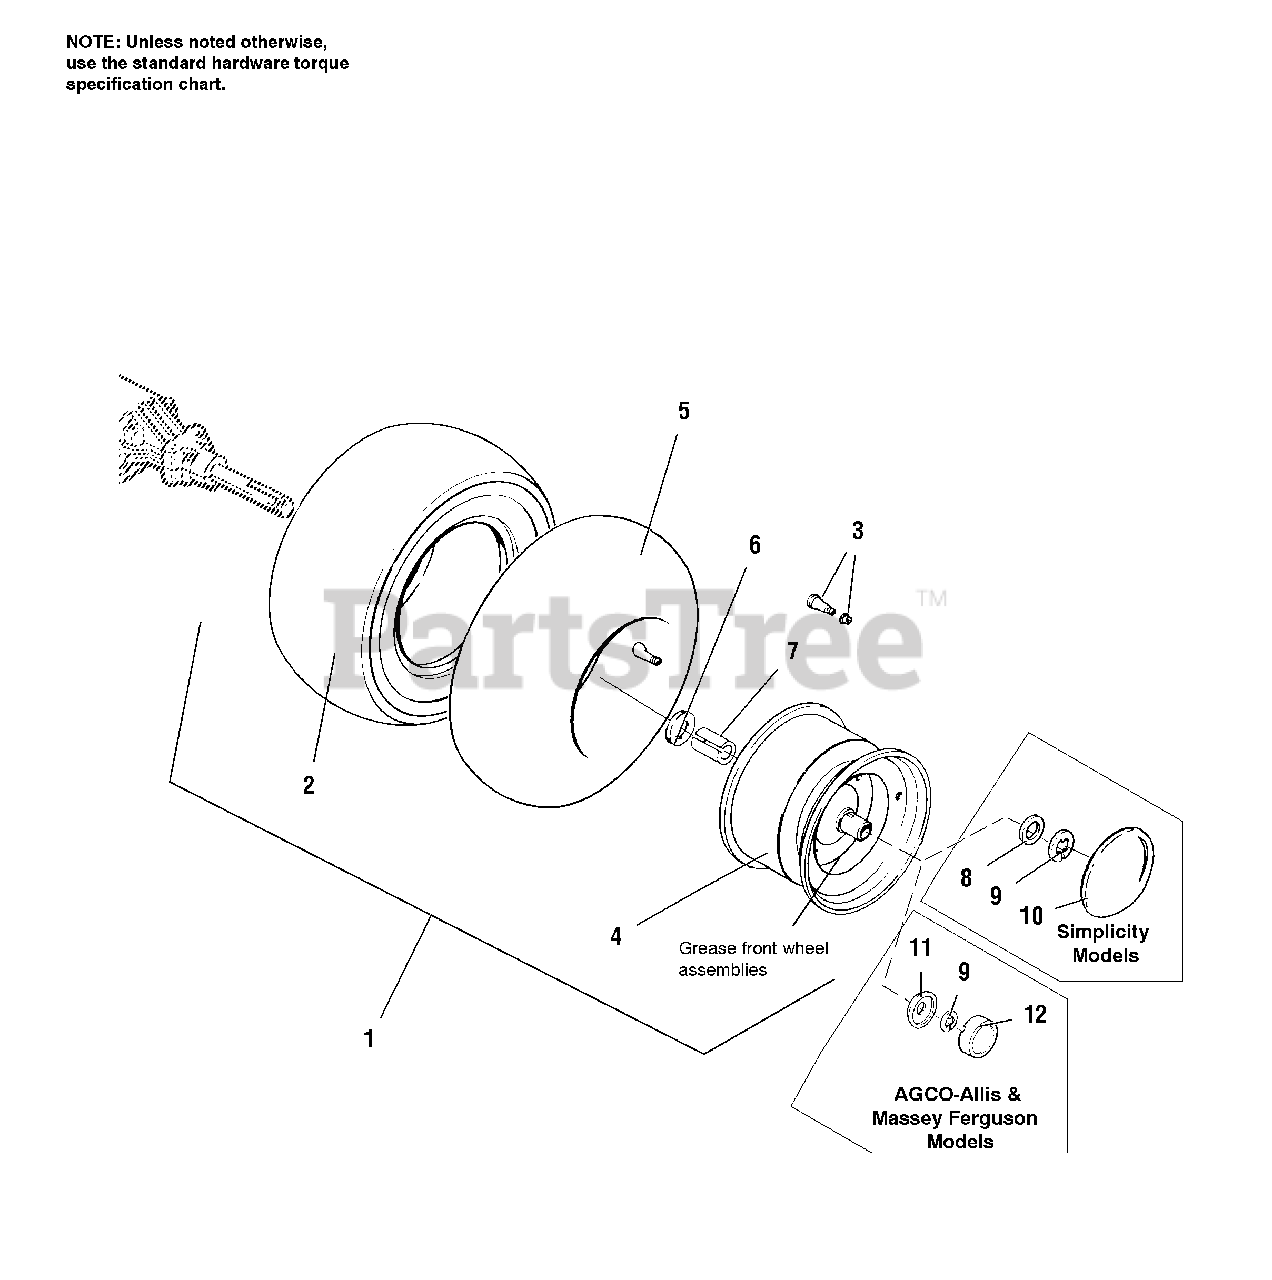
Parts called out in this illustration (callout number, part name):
1	WHEEL & TIRE ASSY., 20 x 8.00-8
2	TIRE, 20 x 8.00-8
3	VALVE STEM & CAP
4	WHEEL ASSY., 20 x 8.00-8
5	TUBE
6	WASHER, 3/4
8	WASHER, 3/4
9	E-Ring
10	HUB CAP, 8"
11	RETAINER, Cap, Hub
12	CAP, Hub
